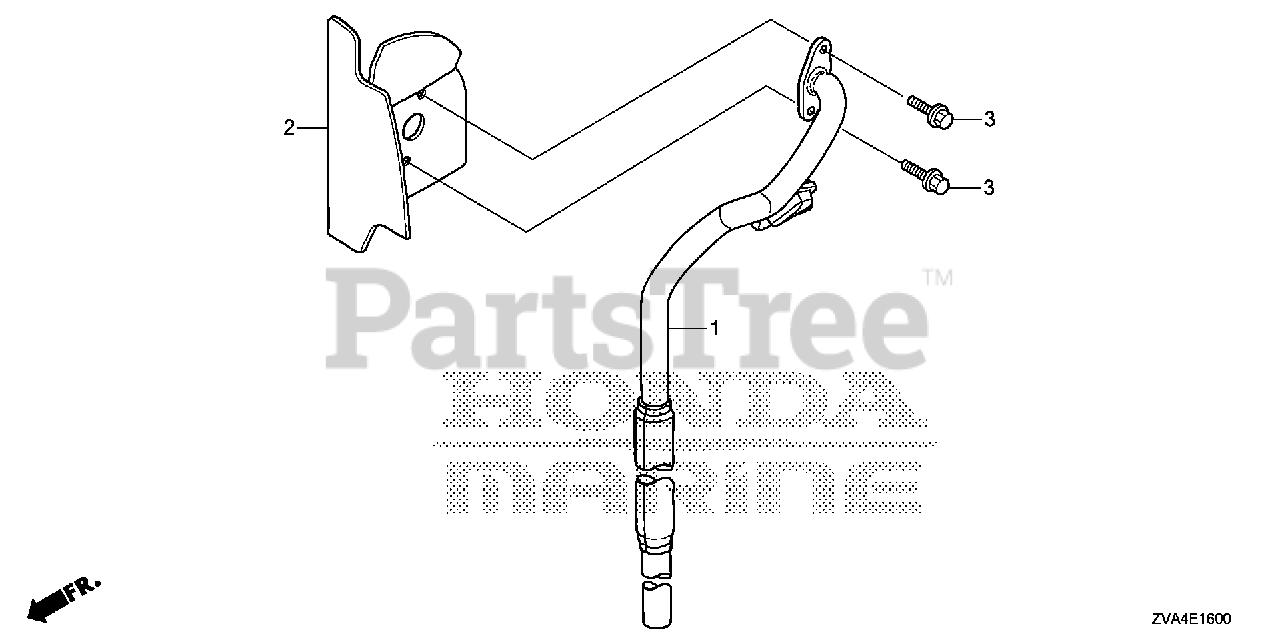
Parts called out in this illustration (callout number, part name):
1	PIPE, EX.
2	GUIDE, AIR EX.
3	BOLT, FLANGE (5X16) (SUS)
